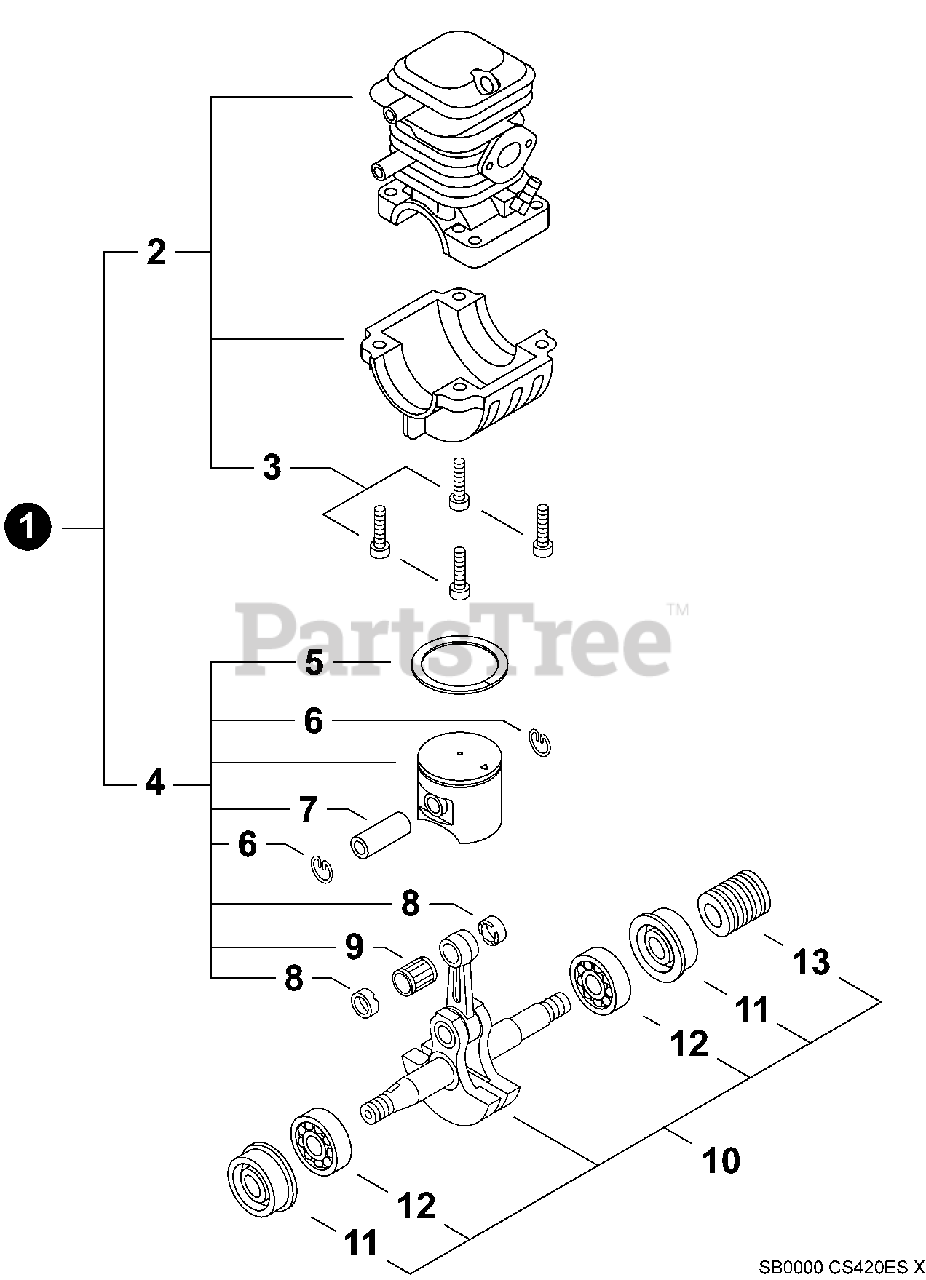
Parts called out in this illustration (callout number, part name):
1	REPAIR KIT, ENGINE
2	CRANKCASE KIT
3	BOLT 5×22
4	PISTON KIT
5	RING, PISTON
6	RING, SNAP
7	PIN, PISTON 9×6×33.8
8	WASHER, THRUST 9×12×15×3
9	BEARING, NEEDLE 9
10	CRANKSHAFT ASSY
11	SEAL, OIL 12
12	BEARING, BALL 6201
13	GEAR, WORM
